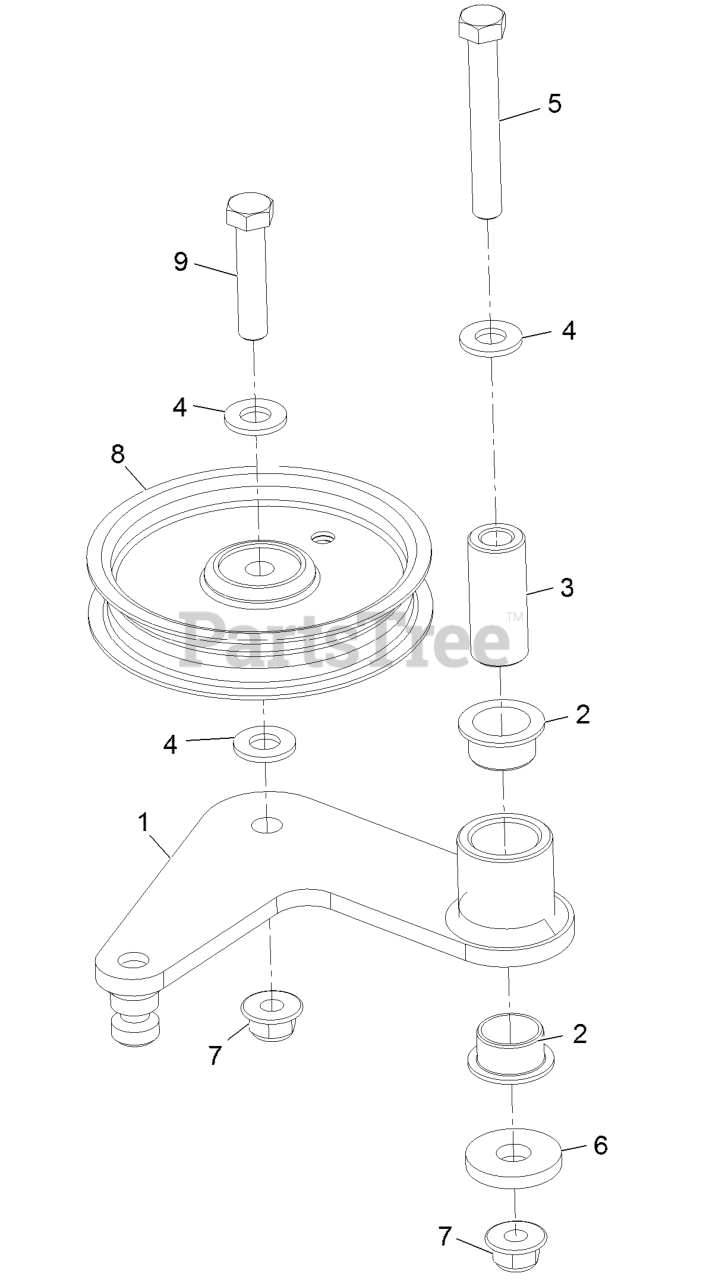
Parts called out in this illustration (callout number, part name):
1	Idler Arm ASM
2	Bushing-Flanged
3	Spacer, Pivot
4	Washer-3/8 SAE
5	Screw-HH 3/8-16 X 2 3/4
7	Nut-Nyloc 3/8-16 Flg
8	Pulley-Idler
9	Screw-HH 3/8-16 X 1 3/4
